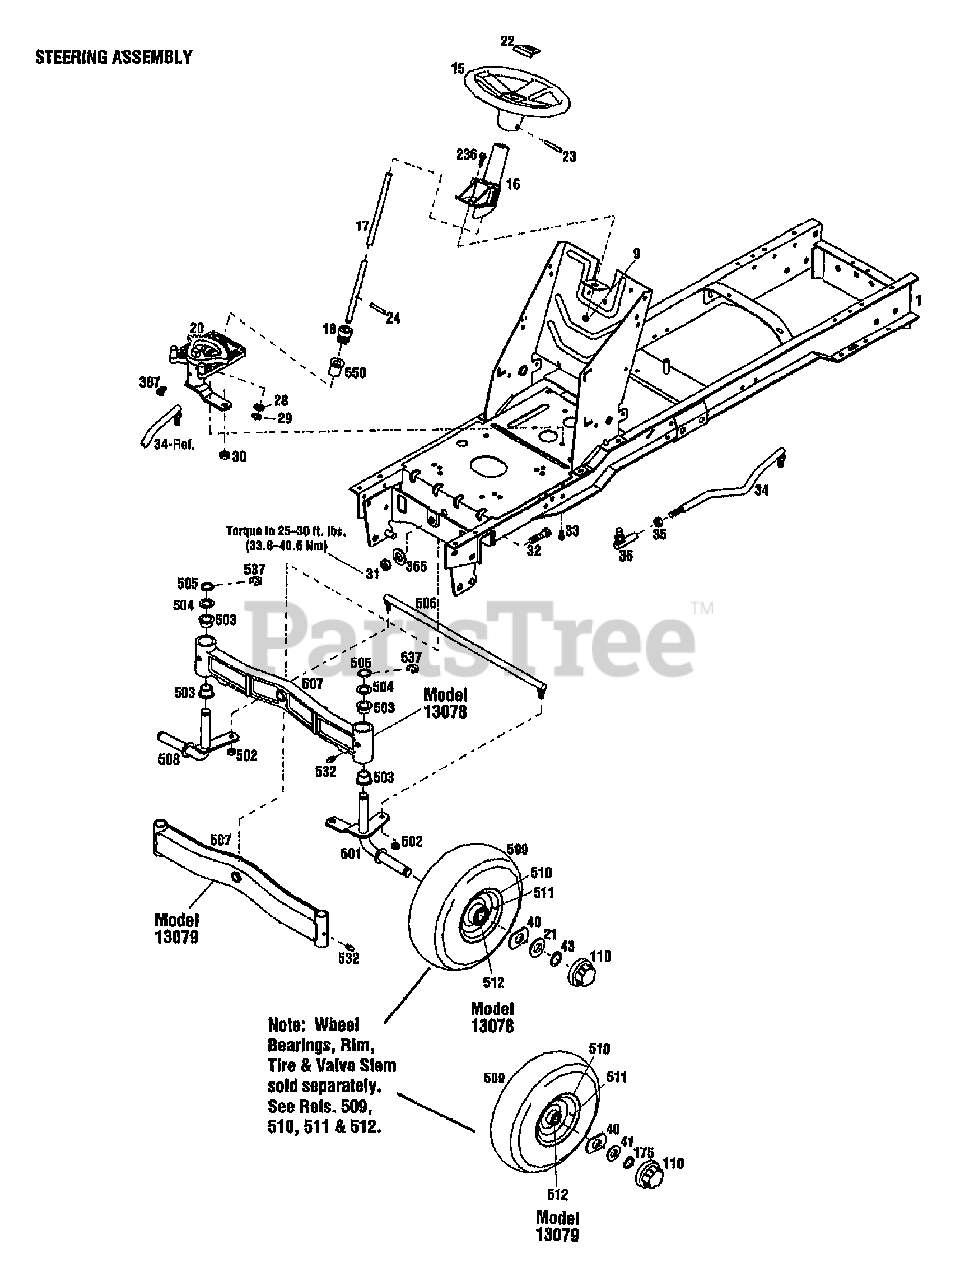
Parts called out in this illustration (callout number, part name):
1	ASSM-FRAME {13078}
1	ASSM-FRAME LTX {13079}
9	NUT-HFLK 5/16-18 ZP
15	WHEEL-STEERING
17	SHAFT-STEERING
18	GEAR-PINION
20	ASSM-STEERING GEAR
21	WASHER-THRUST
22	CAP-STEERING
23	PIN-ROLL .25X2.25
24	PIN-ROLL 1/4 X 1-1/4
28	WASHER-1.0X.64X.09
29	RING-RETAINING
30	NUT-HEX/JAM 1/2-20
31	NUT-H/LK 5/8-11
32	SCR-HH
33	SCR-HFLK 5/16-18X.75
34	LINK-DRAG
35	NUT-JAM
36	JOINT-BALL
40	WASHER-SPEC .75X2.50 {13079}
40	WASHER-SPECIAL .75X2.5 {13078}
41	WASHER-1.38 X.765X .06 ZP
43	RING-HEAVY EXT HD 1.0 ID {13078}
110	CAP-HUB
175	RING-RET."E".577 ID
236	SCR-HFLK 5/16-18X.75 ZP
366	WASHER-1.75X.687X.134 ZP
387	FITTING-GREASE 90 DEGREE
501	ASSM-SPINDLE LH {13079}
501	SPINDLE-WHEEL LH {13078}
502	NUT-LOCK
503	BUSHING {13079}
503	BEARING-FLANGE {13078}
504	WASHER-1.25X.765X.049 {13079}
504	WASHER-THRUST {13078}
505	RING-HEAVY EXT HD 1.0 ID
506	KIT-TIE ROD W/HDW
507	AXLE-FRONT {13079}
507	AXLE-FRONT {13078}
508	ASSM-SPINDLE WHEEL RH {13079}
508	SPINDLE-WHEEL RH {13078}
509	TIRE 15X6.00-6RS {13079}
509	TIRE-16X6.50-8 {13078}
510	RIM-WHEEL {13078}
510	DISC WHEEL {13079}
511	STEM-VALVE
512	BEARINGS-WHEEL {13079}
512	BEARING-BALL {13078}
532	FITTING-GREASE 1/4-28X2.00
537	RING-RET."E".577 ID {13079}
550	BEARING
